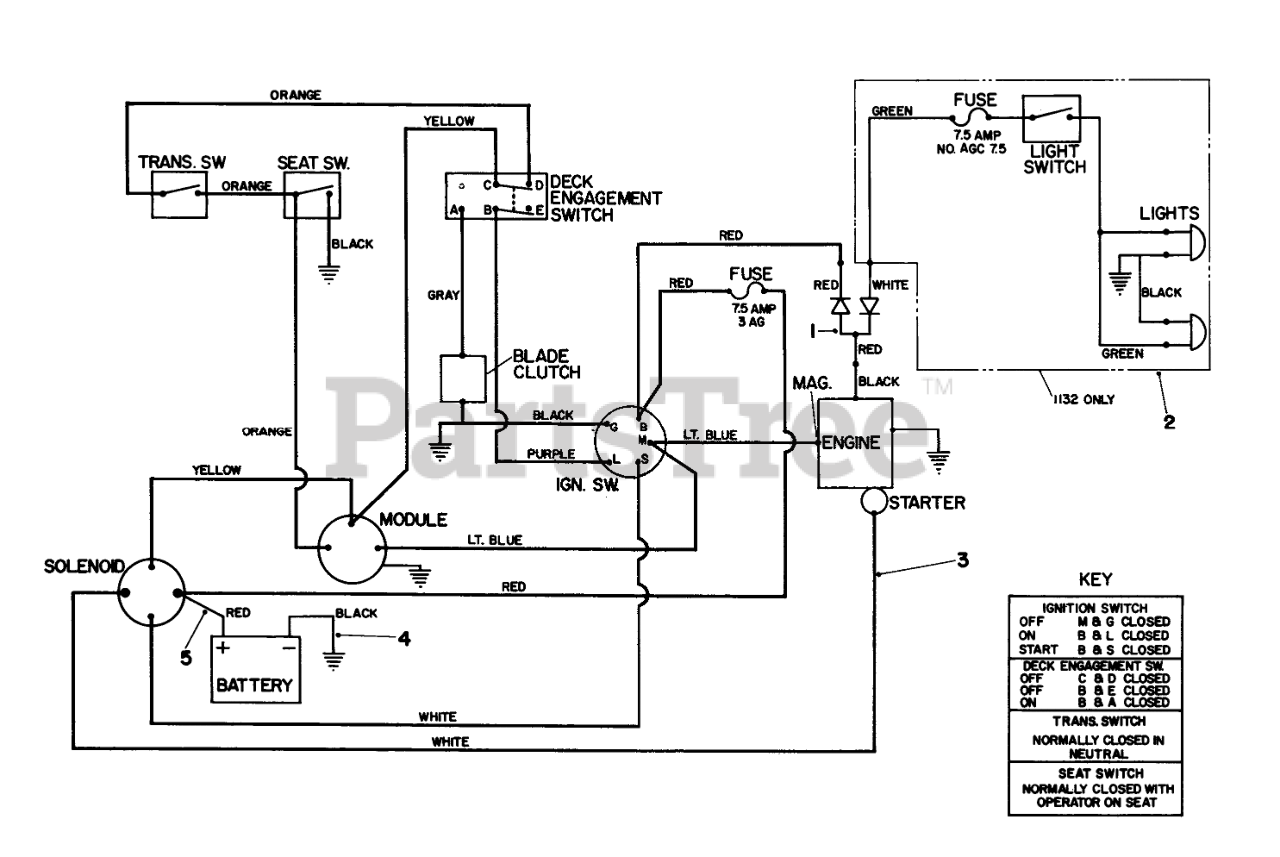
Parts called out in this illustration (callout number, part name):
1	WIRE HARNESS WIRE
2	WIRE HARNESS
3	WIRE HARNESS
4	WIRE ASM
5	WIRE ASM
